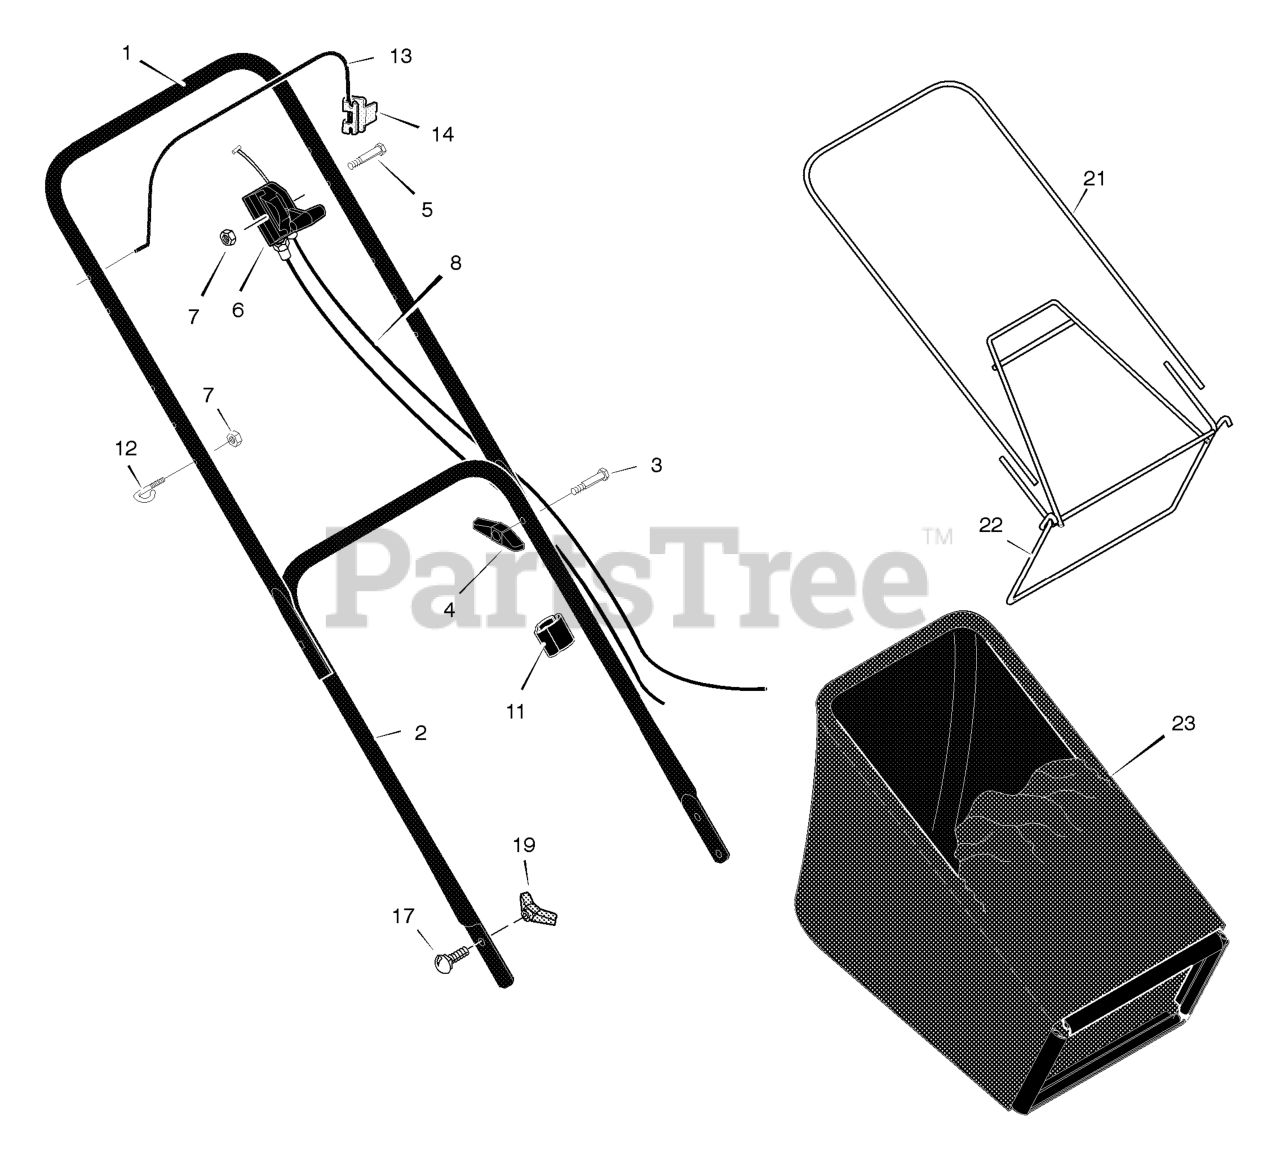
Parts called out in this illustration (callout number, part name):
1	Handle, Upper (Black)
2	Handle, Lower (Black)
4	Knob, Plastic
6	Throttle Control
7	Locknut
8	Engine Stop Cable
11	Clip, Cable
12	Guide, Rope
13	Lever, Engine Stop
14	Bracket, Stop Lever
15	Sleeve, Stop Lever
17	Bolt, Carriage
19	Knob, Plastic
21	Frame, Top
22	Frame Assembly
23	Bag, Cloth
